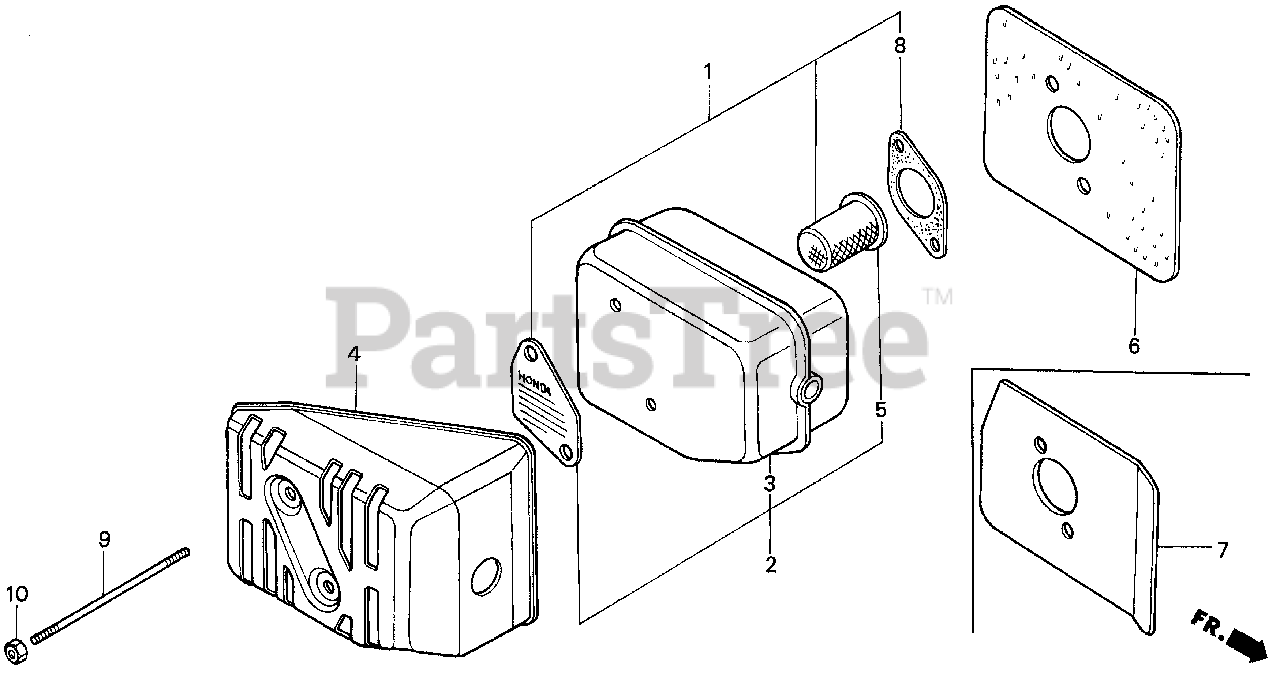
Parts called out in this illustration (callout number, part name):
1	ARRESTER KIT, SPARK (Honda Code 1662550). (NOT AVAILABLE)
1	ARRESTER KIT, SPARK
2	MUFFLER
3	MUFFLER
4	PROTECTOR, MUFFLER
5	ARRESTER KIT, SPARK
6	GASKET, MUFFLER (NOT AVAILABLE)
6	GASKET, MUFFLER
8	GASKET, MUFFLER (Honda Code 1662568). (NOT AVAILABLE)
8	GASKET, MUFFLER
9	BOLT, STUD (6X81)
10	NUT, SELF-LOCK (6MM)
